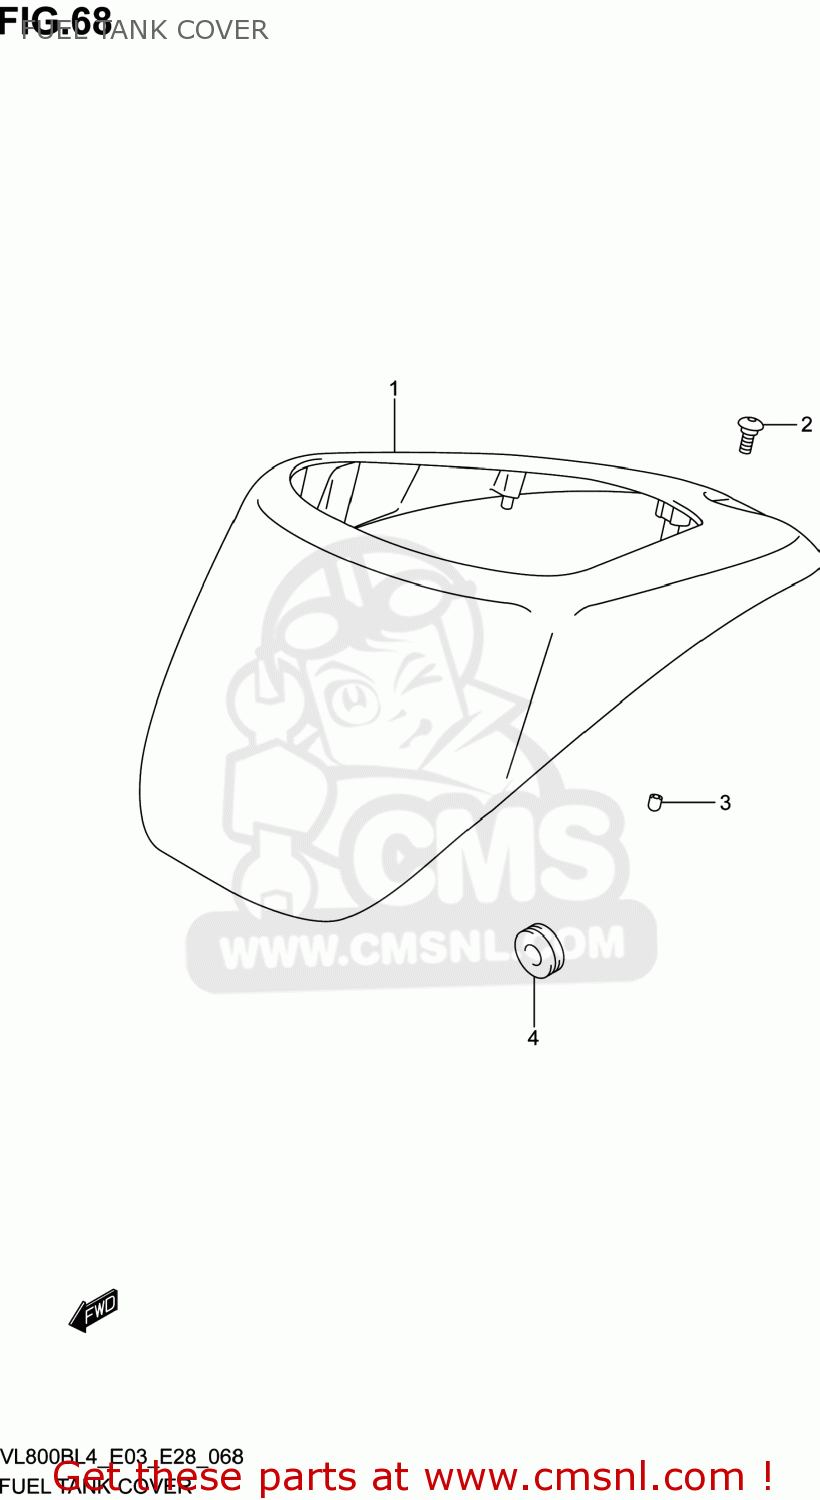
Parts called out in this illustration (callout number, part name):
1	COVER,FUEL TANK UPPER
2	SCREW(5X13)
3	CUSHION,FUEL TANK COVER
4	CUSHION
